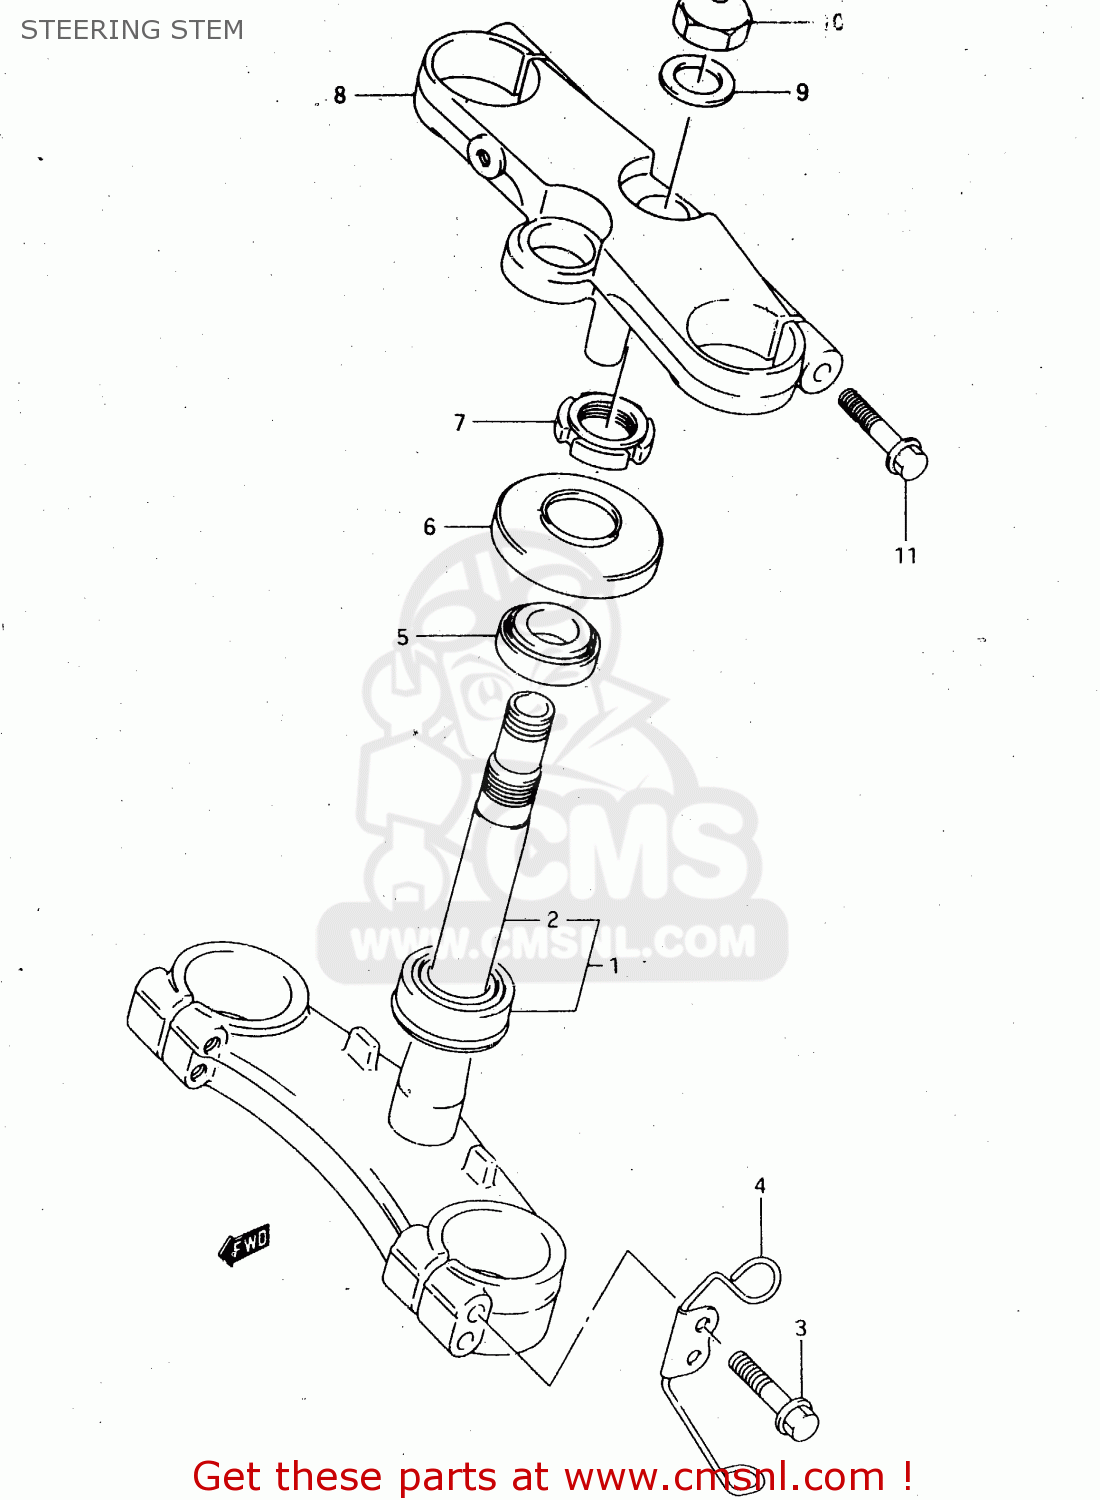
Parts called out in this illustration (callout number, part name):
1	STEM,STEERING
2	BEARING(30X55X17)
3	BOLT
4	CLAMP, METER CABLE
5	TAPER,ROLLER BEARING
6	SEAL,OIL(34X69X11.9)
7	NUT,STEERING STEM(25X44X10)
8	HEAD,STEERING
9	WASHER(22.5X32X1.6)
10	NUT
11	BOLT
